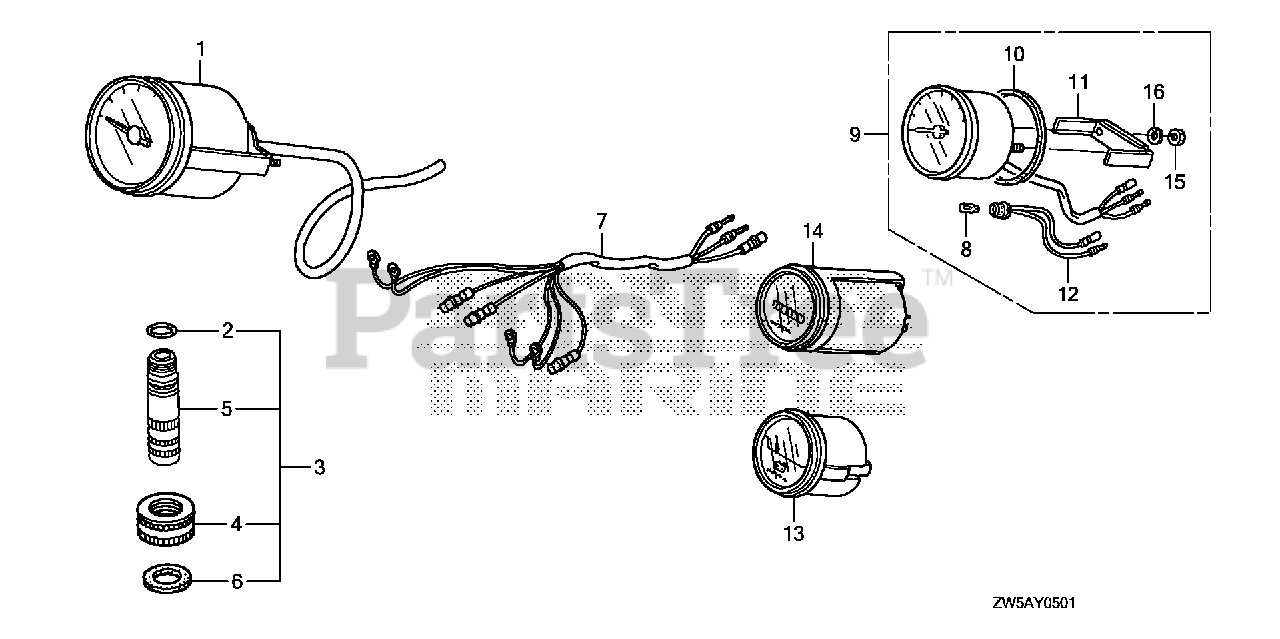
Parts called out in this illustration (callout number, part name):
1	SPEEDOMETER KIT
2	O-RING (11.8X2.4)
3	JOINT ASSY., HOSE
4	NUT, WATER MOUTH
5	JOINT ASSY., HOSE
6	SEAT, WATER MOUTH
7	HARNESS ASSY., METER (B)
8	BULB, WEDGE BASE (T10) (12V 1.7W) (STANLEY)
9	TACHOMETER ASSY.
10	GASKET
11	BRACKET
12	SOCKET
13	METER ASSY., VOLT (NOT AVAILABLE)
14	METER ASSY., HOUR L.C.D.
15	NUT, HEX. (5MM)
16	WASHER, SPRING (5MM)
